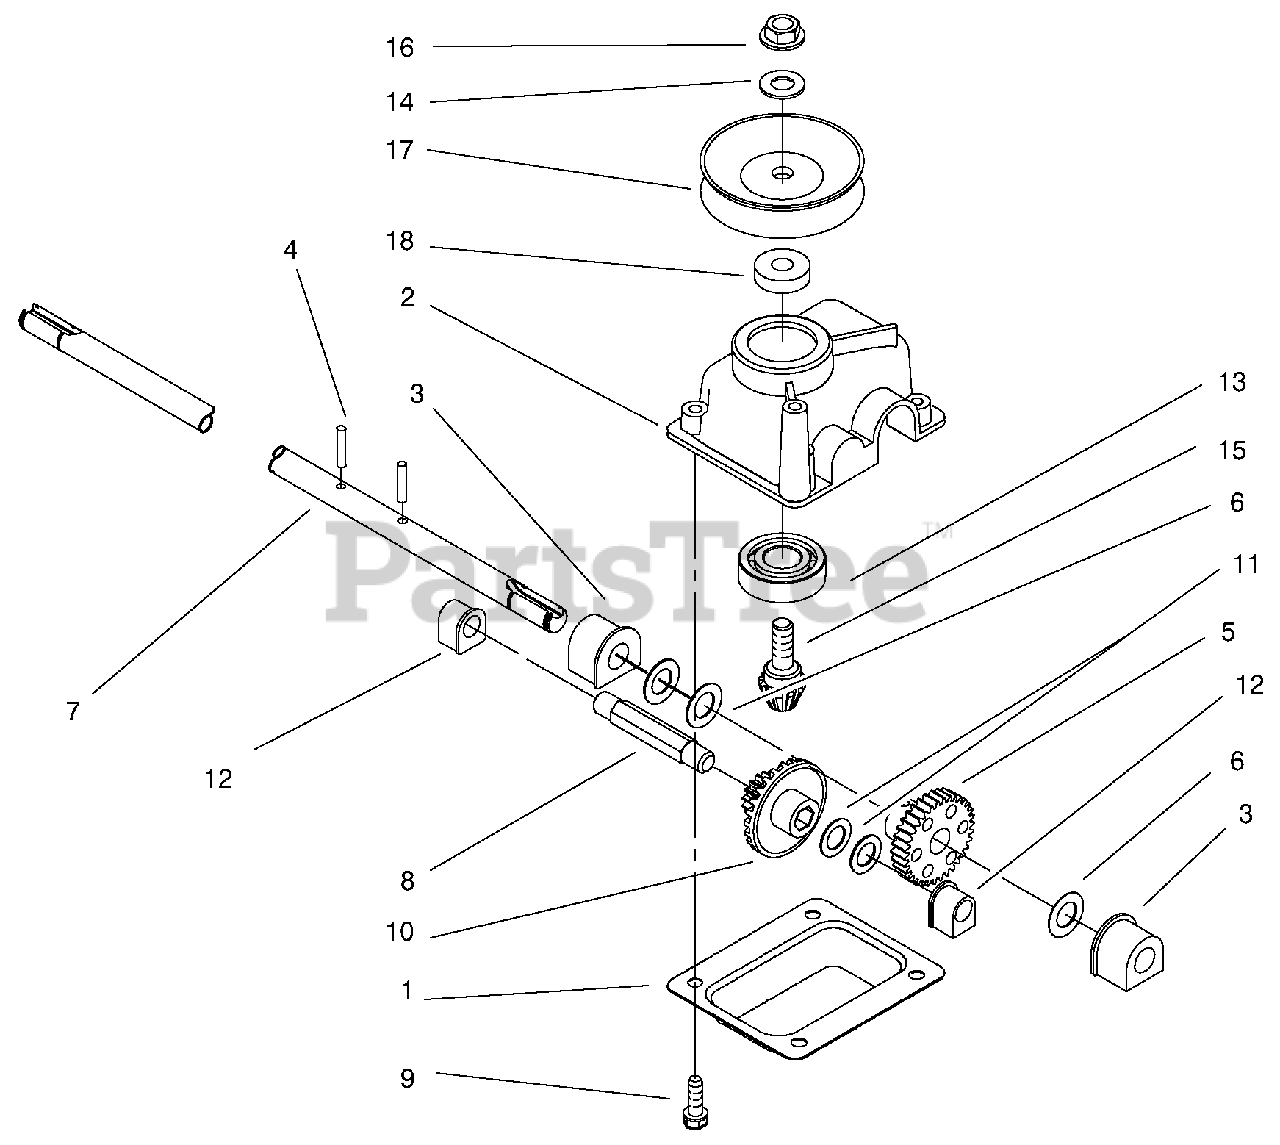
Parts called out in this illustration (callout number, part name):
1	Cover-Gear Case
2	Gearcase
3	Bushing-Output
4	Pin-Groove
7	Shaft-Output
8	Shaft-Intermediate
9	Screw-Taptite
10	Gear-Bevel
11	Washer-Thrust
13	Bearing-Ball
14	Washer-Flat
15	Gear-Bevel, Pinion
16	Nut-Lock, NI
17	Pulley-Half
